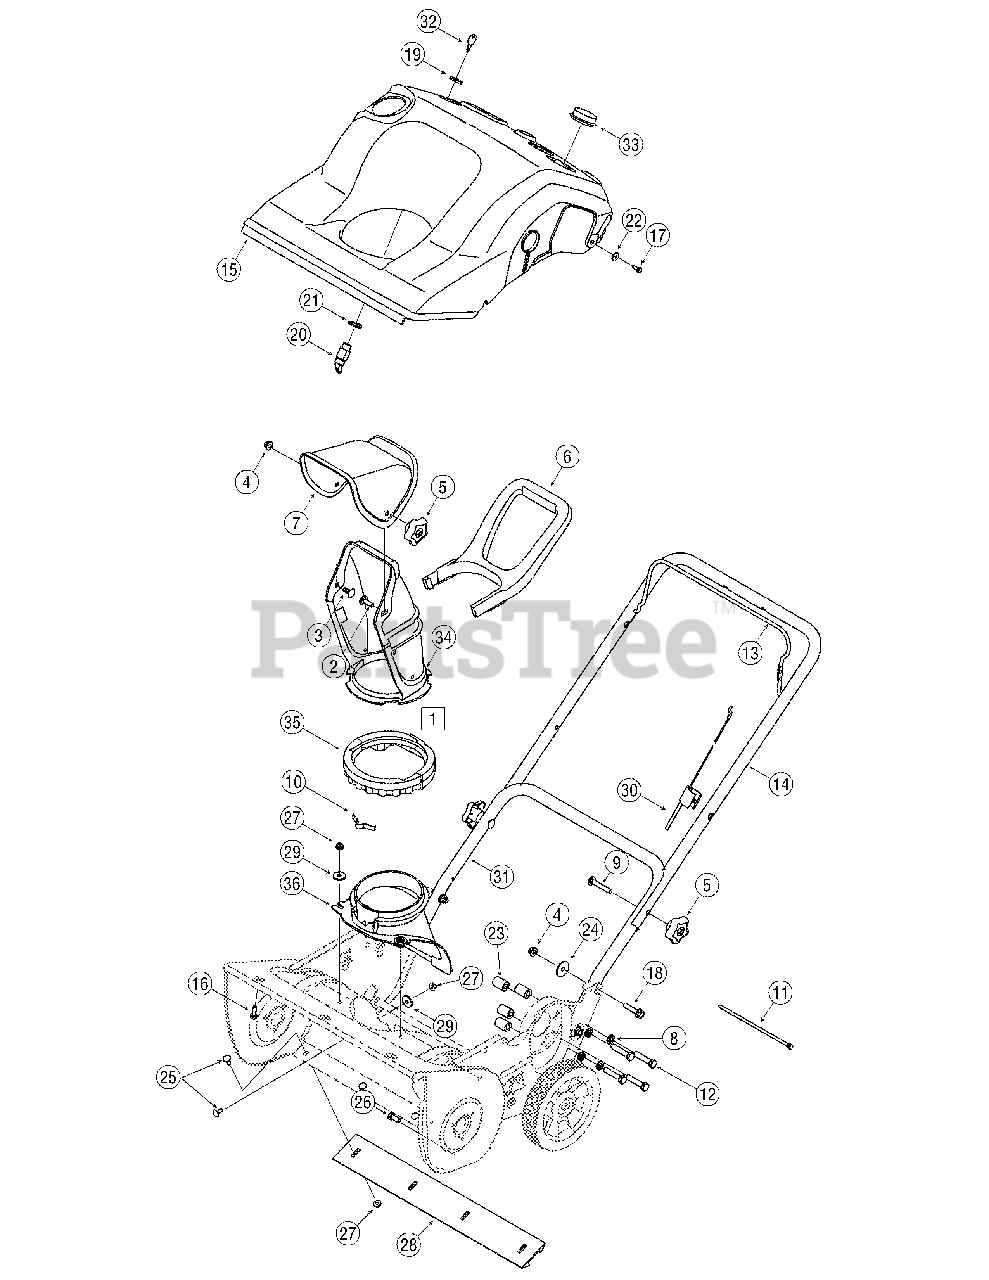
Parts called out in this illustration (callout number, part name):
1	Chute Assembly
2	Carriage Bolt 5/16-18 x 1.0"
3	Carriage Bolt 5/16-18 x 0.750"
4	Flange Lock Nut, 5/16-18
5	Star Knob, 5/16-18
6	Chute Handle
7	Upper Chute
8	Lock Washer, 5/16
9	Carriage Screw, 5/16-18 x 2.0 Gr. 5
10	Chute Adjustment Spring
11	Cable Tie
12	Screw, 5/16-18 x 1.50
13	Bail, Gull Wing
15	Shroud Assembly
16	Screw, 1/4-15 x .50
17	Self-tapping Screw, #10-16 x .625"
18	Hex Flange Screw 5/16-18 x 1.50 Gr. 5
19	Hex Nut 5/8-32 x .12 Special
20	Key Switch-Electric Start
21	Lock Washer Internal .625 x 1.058
22	Flat Washer .194" x .62" x .063
23	Spcr., .325 ID x .625 OD x .88 Lg.
24	Flat Washer .330 x 1.25 x .06
25	Screw, 1/4-20 x .62
26	Truss Machine Screw, 5/16-18 x .75
27	Hex Flange Lock Nut, 1/4-20
28	Shave Plate,19.88
29	Flat Washer .265 x .938 x .120
30	Control Cable
32	Ignition Key
33	Spark Plug Cover
34	Lower Chute 5" Dia
35	Ring-Lower Chute
36	Chute, Adapter 5" Dia
